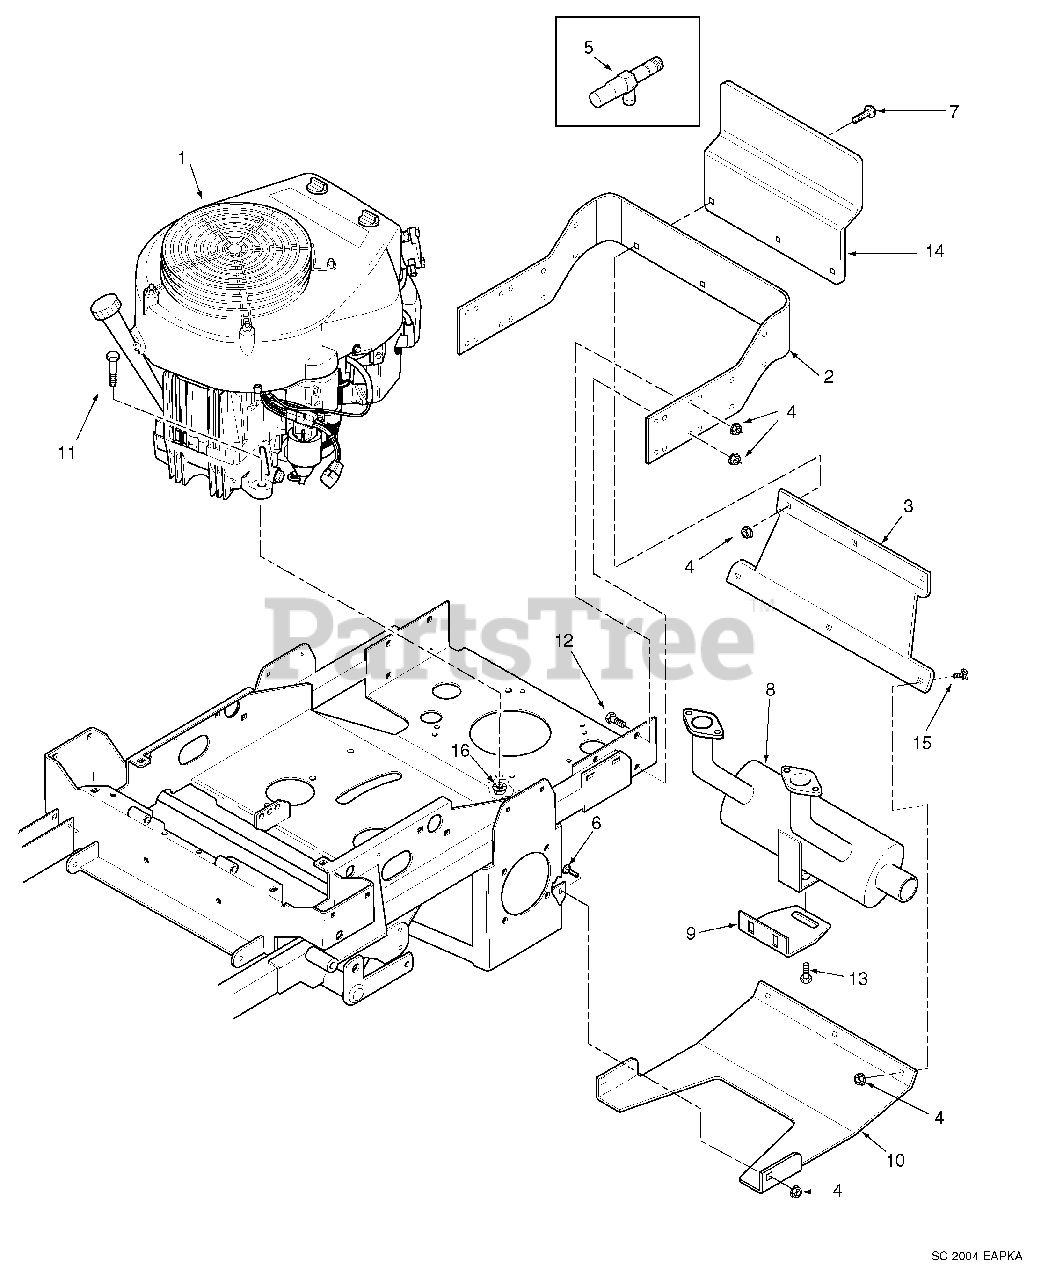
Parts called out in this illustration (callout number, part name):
1	Engine, Kohler Command 25hp
2	Bumper, Rear
3	Weight, Rear (Shield) 61V Only
4	Nut, Serr. Flng. 3/8-16
5	Extension, Oil Drain 4"
6	Bolt, Carr. 3/8-16 x 1"
7	Bolt, Hex Hd. 3/8-16 x 1-1/4"
8	Muffler
9	Bracket, Muffler
10	Plate, Skid
11	Bolt, Hex Hd. 5/16-18 x 1-1/2"
12	Bolt, Hex Hd. 3/8-16 x 1"
13	Screw, 5/16-18 x 3/4"
14	Guard, Carb Inlet
15	Bolt, Hex Hd. 3/8-16 x 1-1/4"
16	Nut, Serr. Flng. 5/16-18
